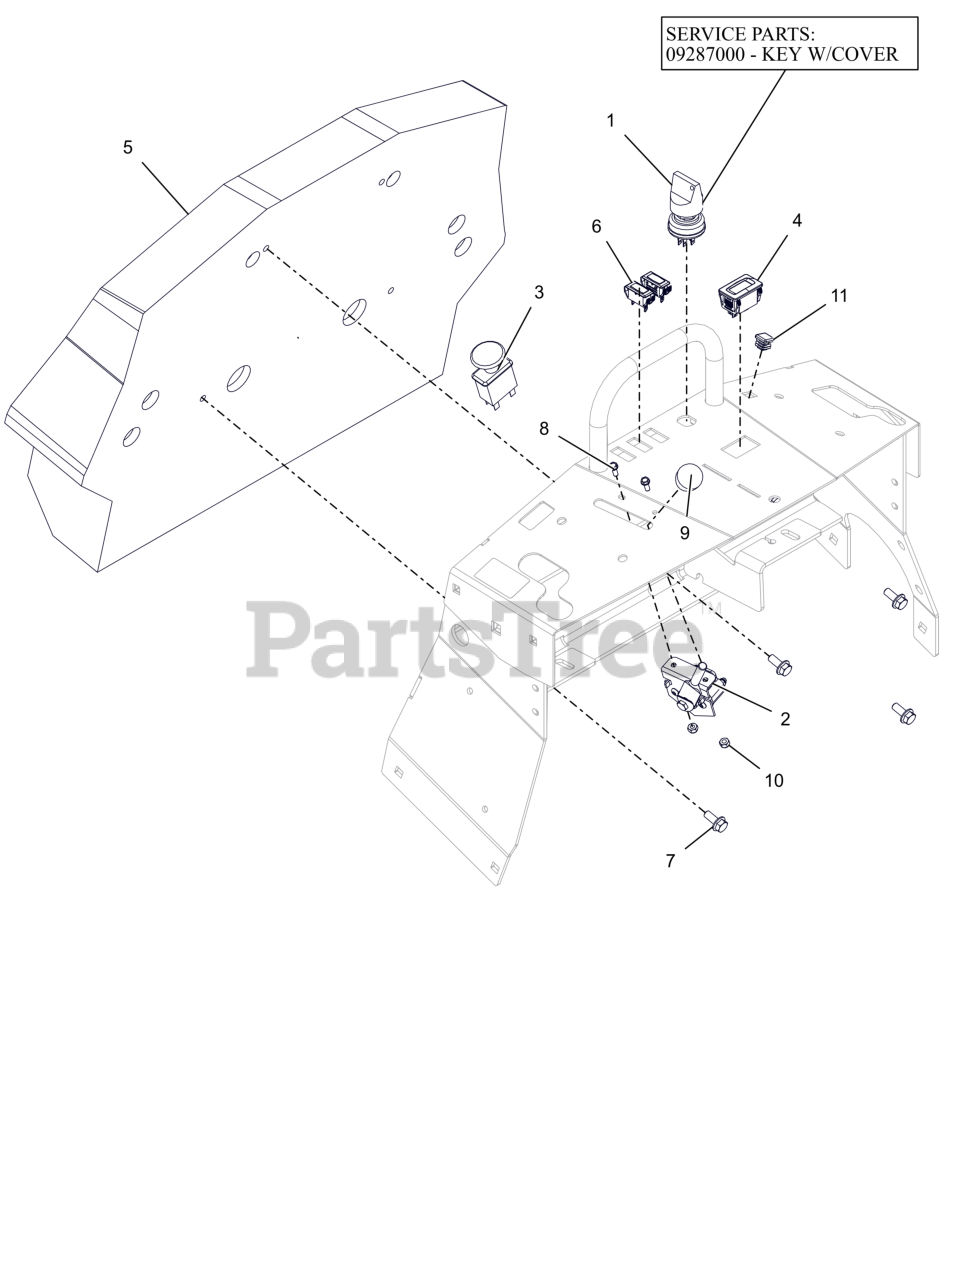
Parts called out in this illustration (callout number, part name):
1	SWITCH, IGNITION
2	CONTROL, ELECTRONIC THROTTLE
3	SWITCH, CLUTCH
4	HOUR METER
5	PAD, OPERATOR - PROSTANCE
6	LIGHT,INDICATOR
7	BLT, SERHFWH 0.312-18X0.75 GR5 ZCC
8	BLT, HWH #10-24X.50 ZCC
9	KNOB-CONTROL-BLACK .38-16X.50
10	NUT-LK-NYL #10-24 G2 ZCC
11	PLUG, 5/8" SQ BLACK (14-20GA)
